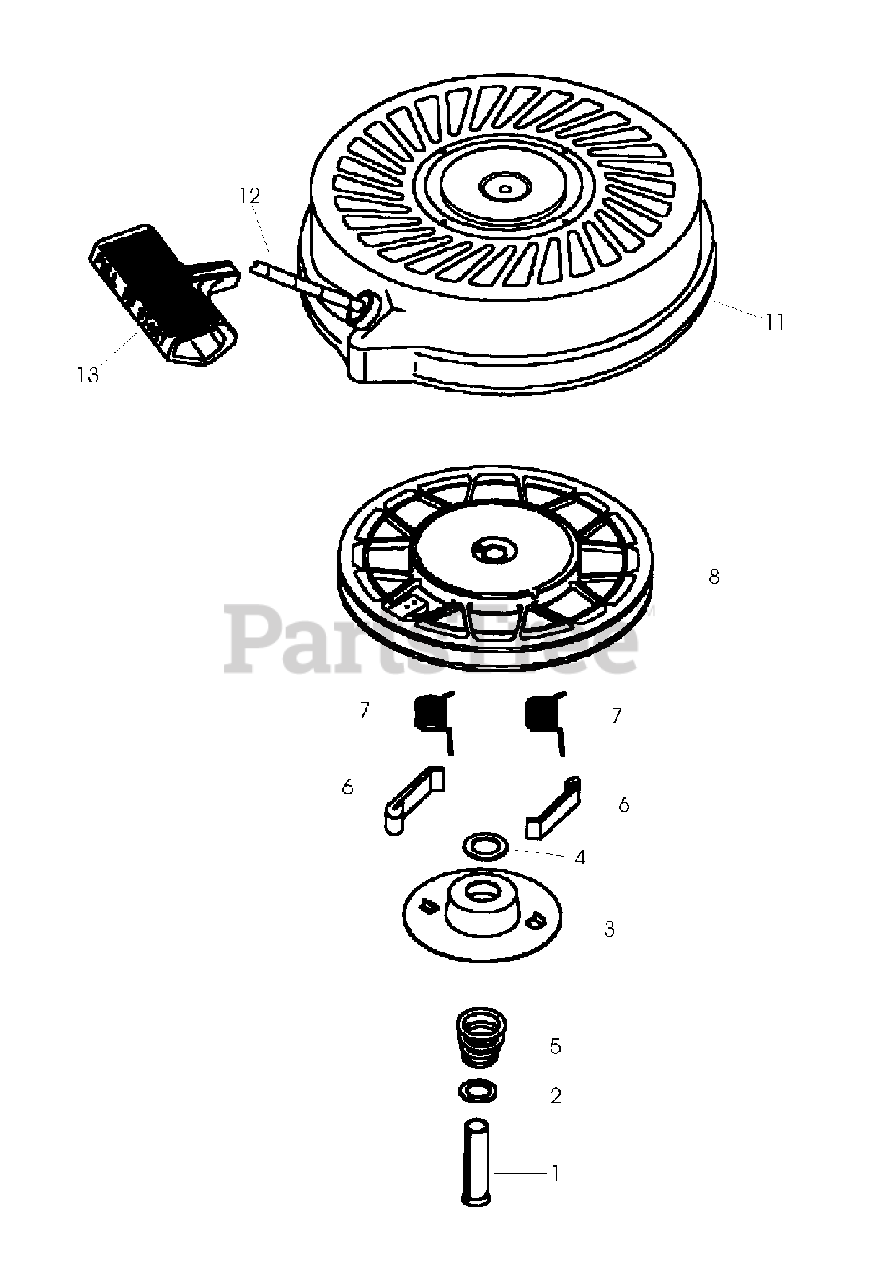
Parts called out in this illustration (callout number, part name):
1	Spring Pin
3	Retainer
5	Brake Spring
6	Starter Dog
7	Dog Spring
8	Pulley & Rewind Spring Assembly
11	Starter Housing Assembly
12	Starter Rope
13	Starter Handle
